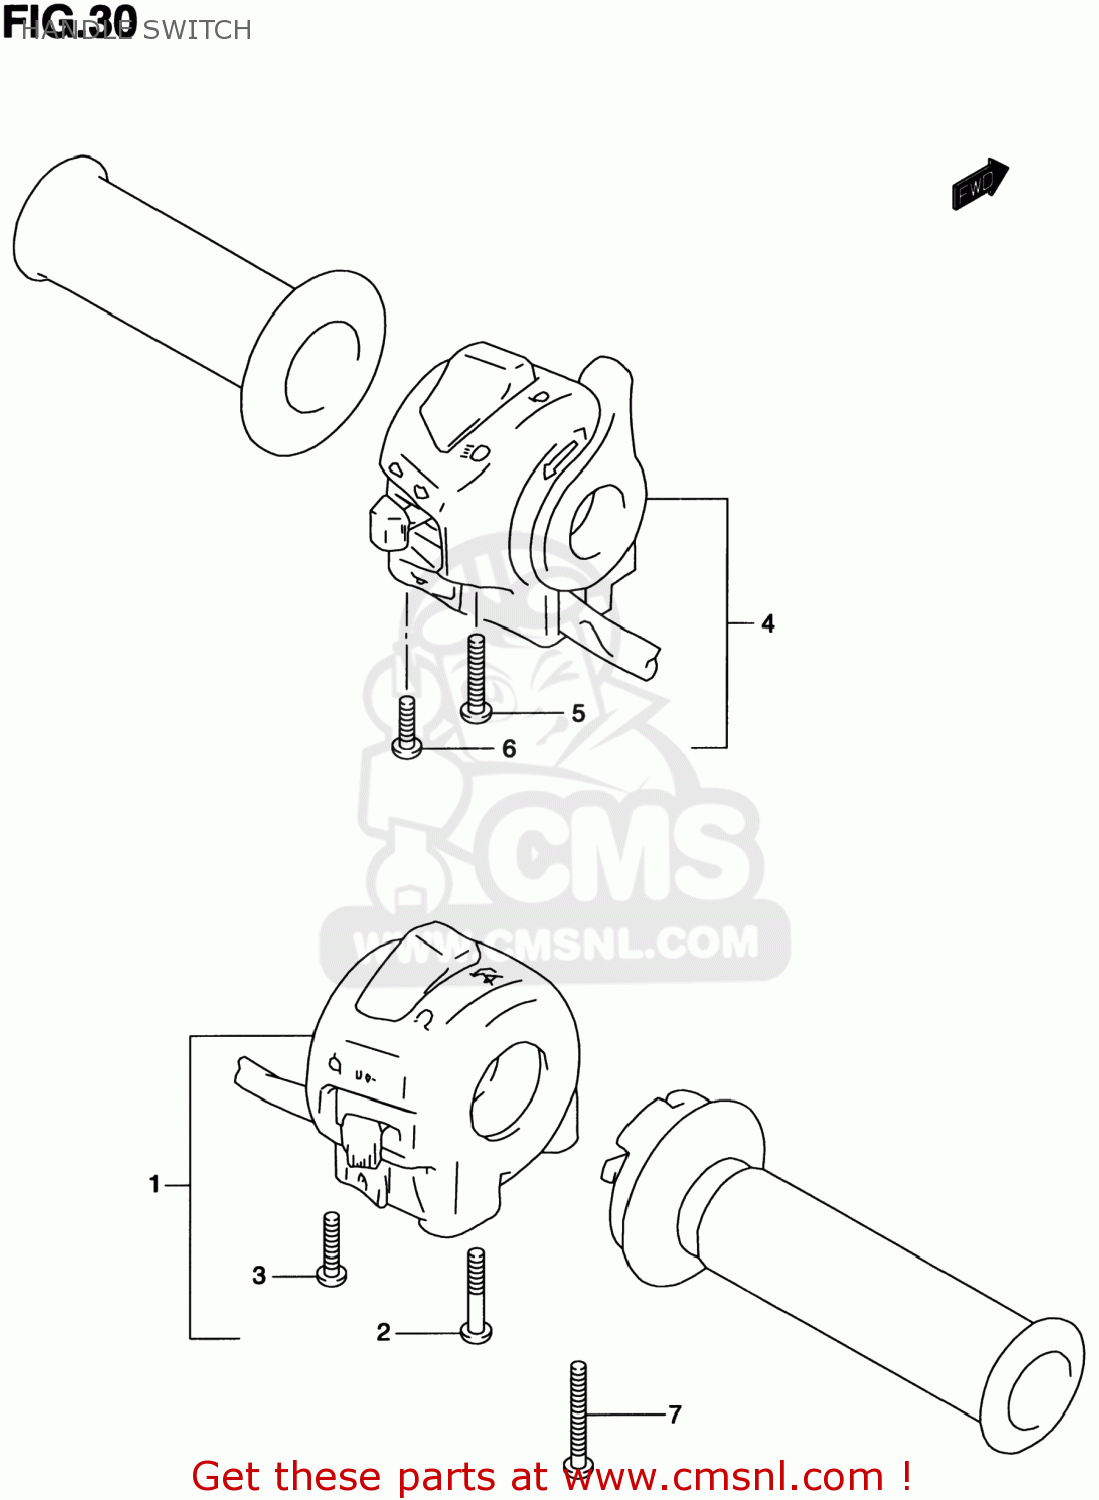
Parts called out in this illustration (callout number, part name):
1	SWITCH ASSY,HANDLE,R
2	SCREW
3	SCREW
4	SWITCH ASSY,HANDLE,L
5	SCREW
6	SCREW, 5X45
7	SCREW
